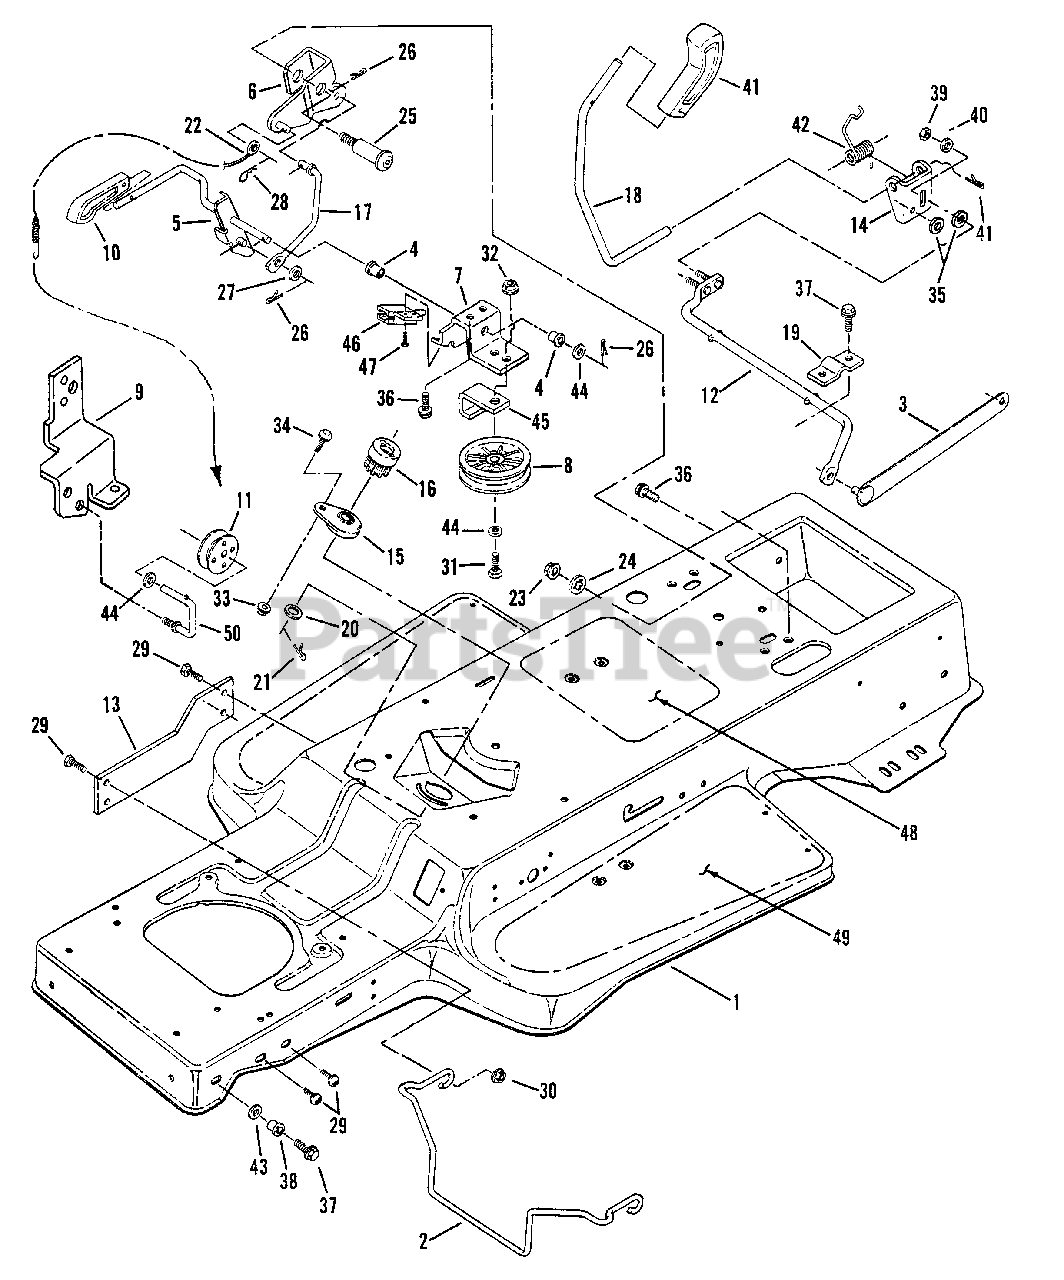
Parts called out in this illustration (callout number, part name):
1	FRAME, Tractor
2	GUIDE, Belt
3	LINK, Shift
4	BUSHING
5	WELDMENT. PTO Lever
6	WELDMENT, PTO Bellcrank
7	SUPPORT, PTO LEVER
8	PULLEY
9	BRACKET, Spool
10	KNOB, Deck Engagement
11	SPOOL
12	ASSEMBLY, Shift Lever (Lower)
13	BRACE, Frame
14	BRACKET, Shift Lever (Upper)
15	ASSEMBLY, Steering Adjuster
16	GEAR, Steering Pinion
17	ROD, PTO Link
18	LEVER, Shift
20	WASHER, 1/2 Shim
21	PIN, 1/8 x 3/4" Cotter
22	CABLE, Blade 14.3"
22	CABLE, Blade 20.5"
23	NUT, 1/2-13 Hex Flange Lock
24	WASHER, 1/2 Internal Tooth Lock
25	BOLT, 1/2-13 x 2 11/32" Shoulder
26	PIN, 3/32 x 3/4" Cotter
27	WASHER, 3/8" Flat
28	PIN, 3/32 x 1 1/2" Hair
29	SCREW, 5/16-18 x 5/8" Truss Head, Torx
30	NUT, 5/16-18 Hex Flange Lock
31	SCREW, 3/8-16 x 1 1/2" Hex Head Cap
32	NUT, 3/8-16 Hex Center Lock
33	NUT, 1/4 Hex Flange Lock
34	BOLT, 1/4-20 x 5/8" Short Neck Carriage
35	WASHER,1/4 Internal Tooth Lock
36	SCREW, 5/16-18 x 5/8" Self-Tapping
37	SCREW, 5/16-18 x 1 1/4" Self-Tapping
38	BUSHING, Flange
39	NUT, 1/4-20 Hex Flange Lock
40	WASHER, 1/4 Flat
41	KNOB, Deck Lift Lever
42	SPRING, Shift Lever
43	WASHER, 5/16 Flat
44	WASHER, 3/8" Flat
45	GUIDE, Belt
46	SWITCH, Blade Engagement
47	SCREW, #10-24 x 1/2" Hex Washer Self-Tap (Torx)
48	DECAL, Instruction/Safety
49	PAD, Foot Sandpaper
50	ROD, Spool Pivot
